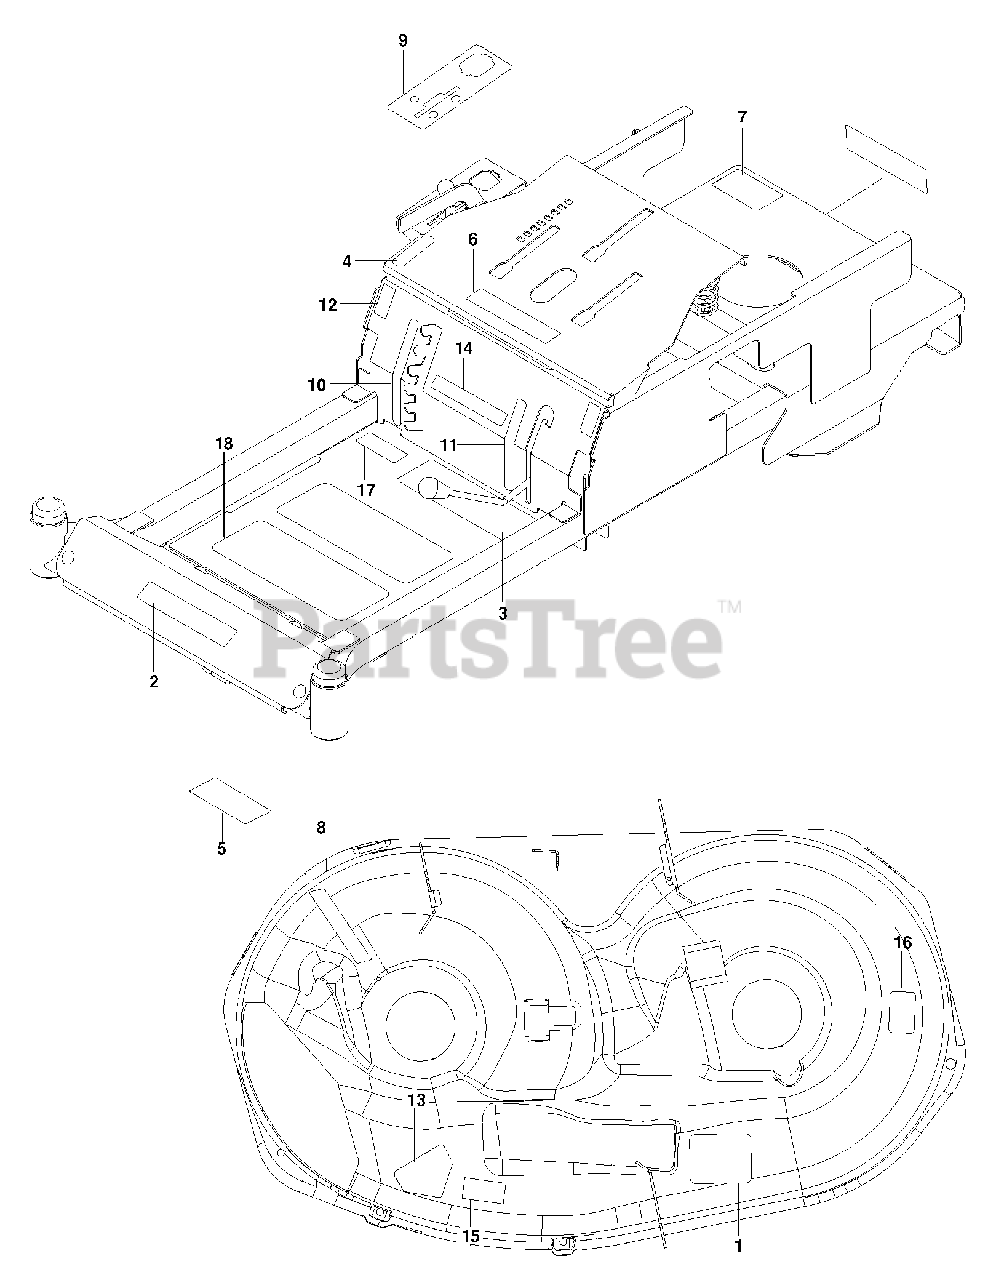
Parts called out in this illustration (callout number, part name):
1	DECAL, BELT ROUTING
3	DECAL, SAFETY WARNING
4	DECAL, PARK BRAKE
5	DECAL, SERVICE
7	DECAL, DO NOT MOUNT
9	DECAL, CONTROL PANEL
10	DECAL, DECK HEIGHT
11	DECAL, BLADE ENGAGEMENT
12	DECAL, MOTION CONTROL
13	DECAL, CPSC
14	DECAL, SPEEDZTR 6.5"
15	DECAL, EURO SEVERING
16	DECAL, 42
18	ANTI-SKID PAD
